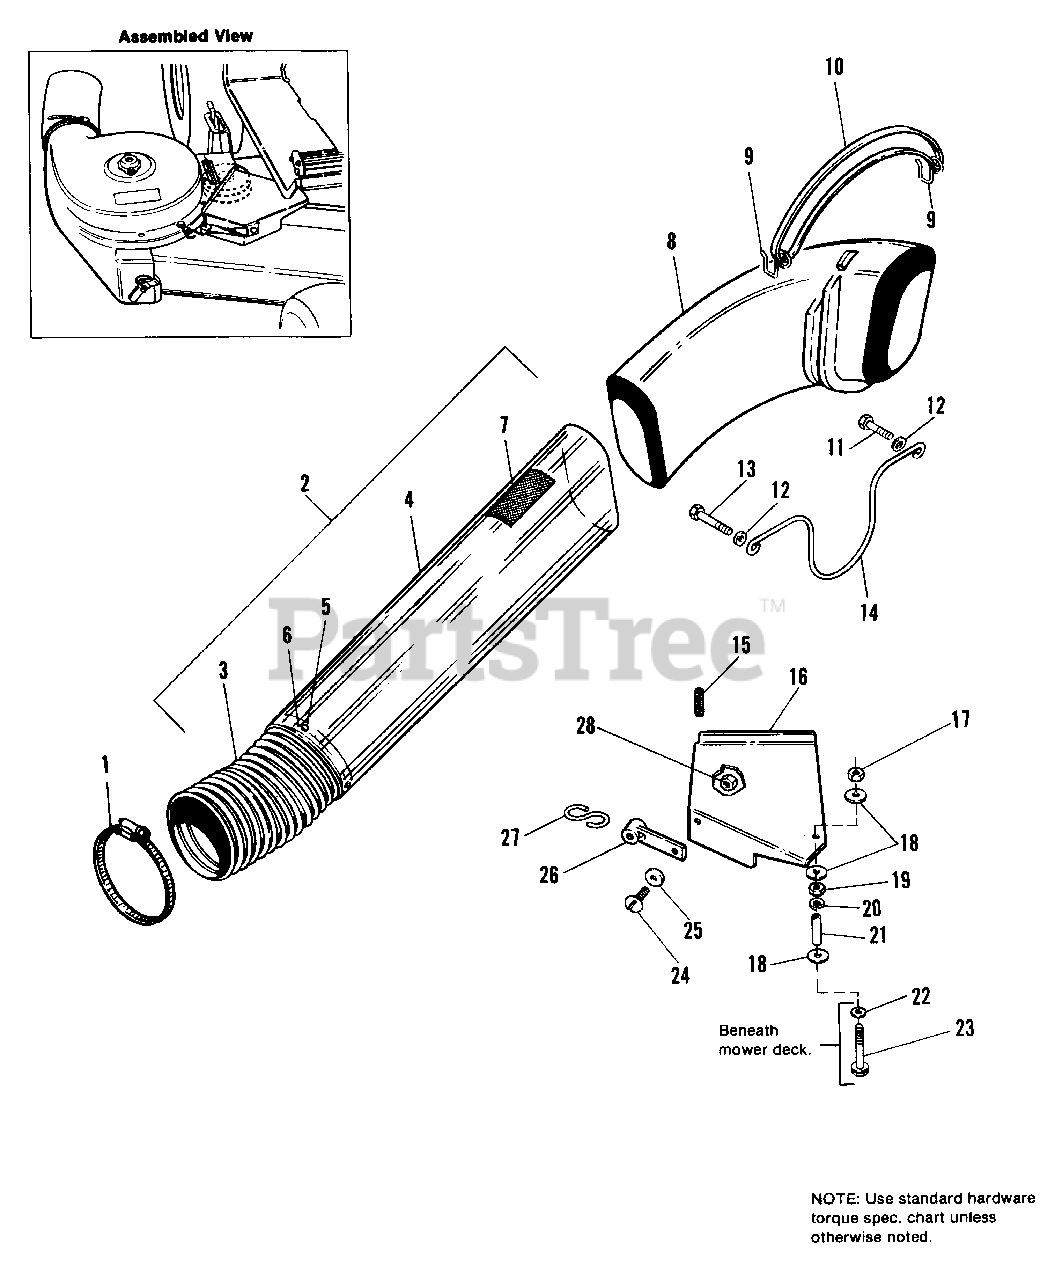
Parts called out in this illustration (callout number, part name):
2	TUBE ASSY., 38" (Incl. Ref. Nos. 3-7)
3	HOSE, Exhaust
6	WASHER, Rivet
7	DECAL, Cleaning Inst.
8	ELBOW, Tube to catcher
9	HOOK, Strap
10	STRAP, Rubber
11	CAPSCREW, Hex Hd., 5/16-18 x 1-1/2
12	WASHER, Plain, 5/16
13	CAPSCREW, Hex Hd., 5/16-18 x 2-1/2
14	SUPPORT, Elbow
16	COVER ASSY, Arbor
17	NUT, Hex, Centerlock, 5/16-18
18	WASHER, 5/16
19	NUT, Hex, Full, 5/16-18
20	LOCKWASHER, 5/16
22	WASHER, Plain, 5/16
23	CAPSCREW, Hex Hd., 5/16-18 x 5-1/2
24	SCREW, Truss Hd., #10-32 x 1/2
25	WASHER, Plain
26	STRAP, Arbor Cover
28	NUT, Hex, Centerlock, #10-32
